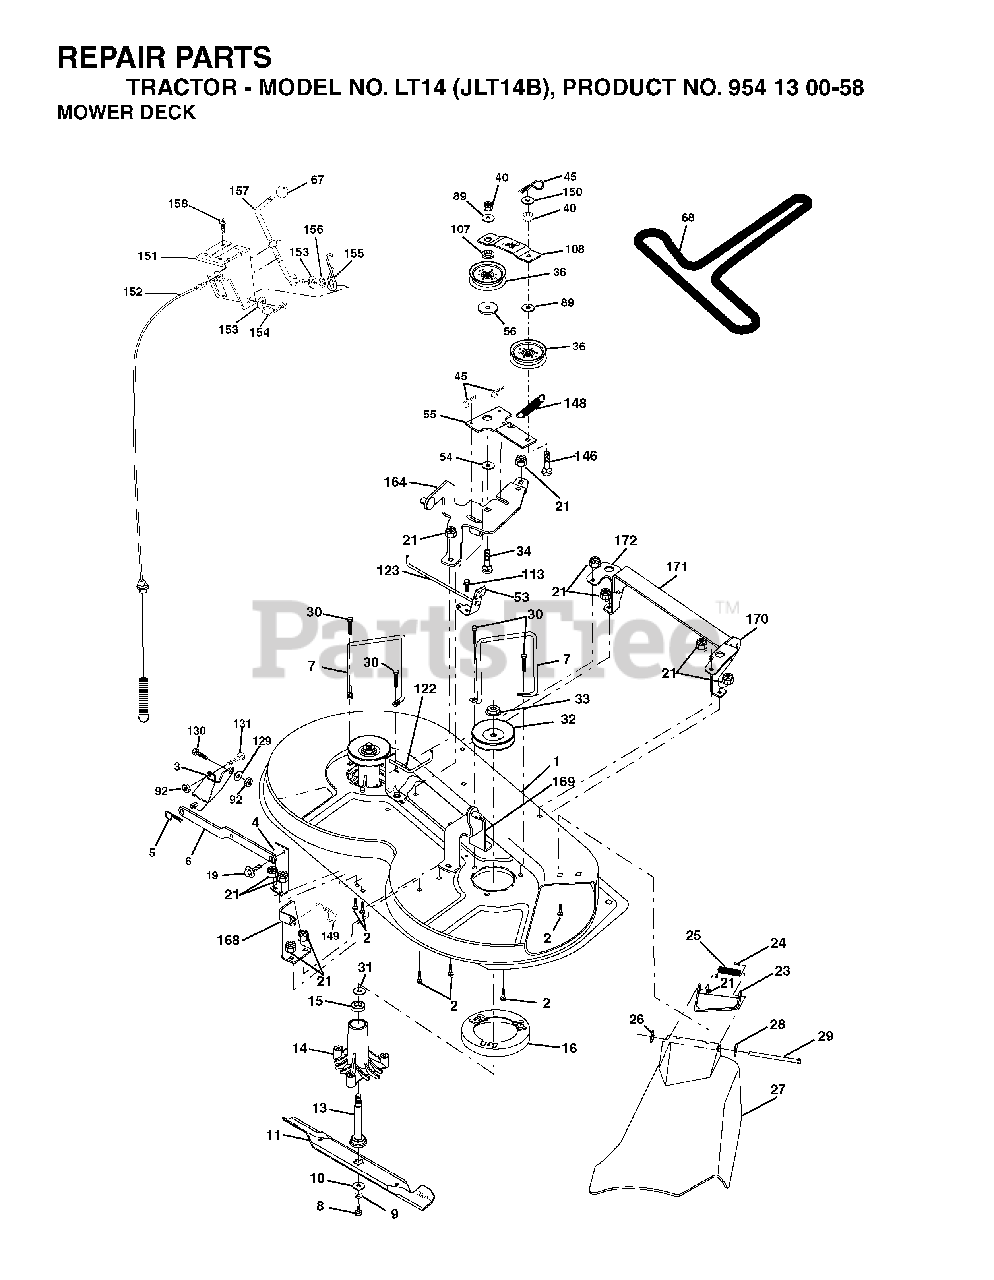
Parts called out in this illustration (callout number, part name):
2	BOLT
3	BRKT ASM SWAY BAR
5	RETAINER-SPRNG RB
6	BAR SWAY DECK
7	KEEPER LH
8	BLADE BOLT
9	LOCKWASHER
10	WASHER.BLADE
11	BLADE, HI-LIFT 36" PREMIUM
13	SHAFT ASM VENT
14	HSG MANDREL
16	STRIPPER, MWR ROUND
19	BOLT SHD 5/16-18
21	LOCKNUT
23	BRACKET ASM DEFLECTOR
24	CAP-SLEEVE LT
25	SPRING TORSION
26	NUT PUSH M
28	WASHER
29	HINGE ROD
30	SCREW, WASHER HEAD
31	WASHER
32	PULLEY, MANDREL
33	NUT, FLG TOPLOCK 9/16"
34	BOLT
36	FLAT IDLER PULLEY
40	LOCKNUT
45	RETAINER M
53	BRAKE ASSEMBLY
55	IDLER ARM
56	SPACER.RETAINER.MOWER
67	KNOB T (3/8 HOLE)
68	V-BELT.MOWER.
89	WASHER GT
92	NUT
107	SPACER.IDLER.ARM
108	STIFFENER.IDLER.ARM
129	WASHER
131	BOLT D
146	BOLT, CARRIAGE IDLER
148	IDLER RETURN SPRING
149	SPRING.RETAINER.YELLOW.ZINC
150	WASHER PM
151	BRACKET, CLUTCH CABLE
153	WASHER FLAT 3/8"
154	SPRING RETAINER
155	SPRING RETENTION LEVER
156	SPACER CLUTCH CABLE
157	ROD CLUTCH CABLE 3/8"
158	SCREW
171	BRACE
